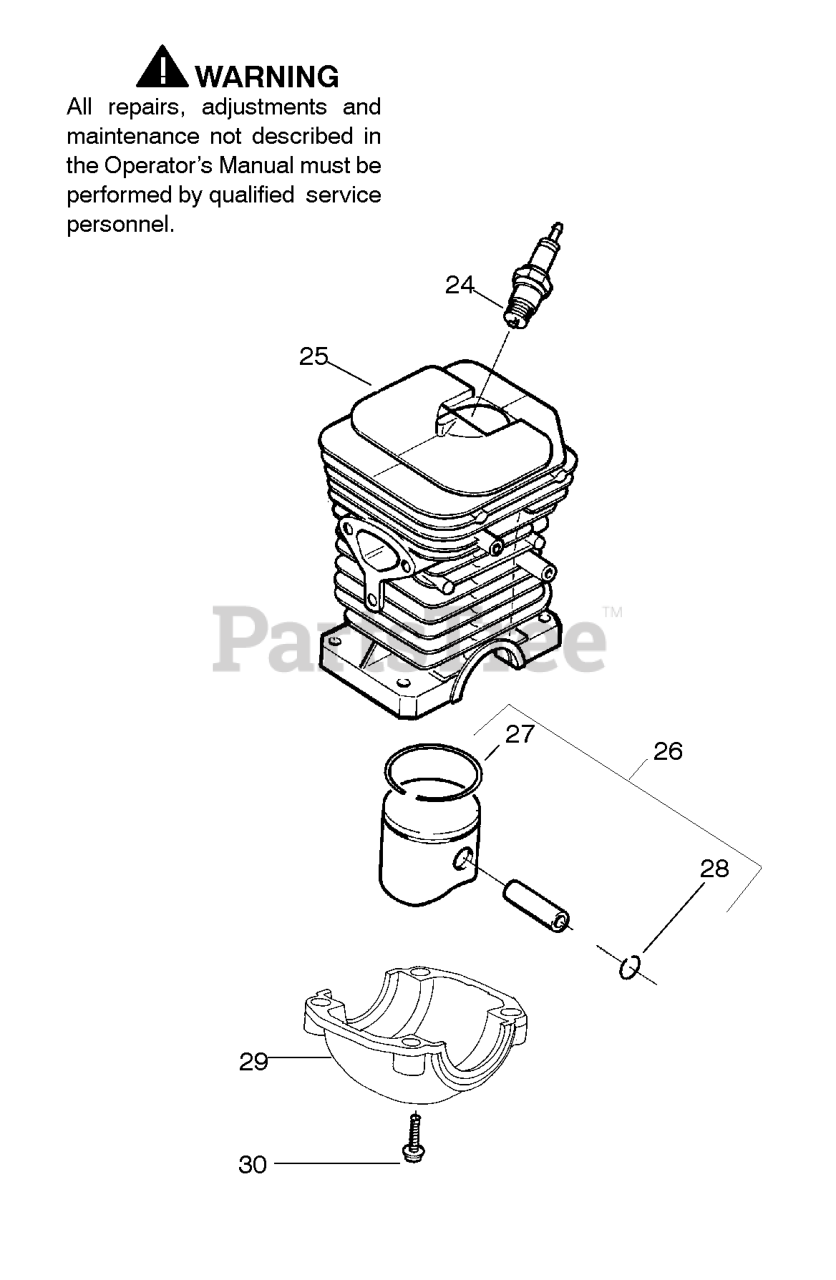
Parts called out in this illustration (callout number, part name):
24	Spark Plug (RCJ-7Y)
25	CYLINDER ASSY/141
26	KIT-PISTON
27	PISTON RING HV41
28	C-CLIP,PSTN PIN 36/41
29	CAP-CRANKSHAFT
30	SCREW-M5-0.8 X 25MM(TAP)
